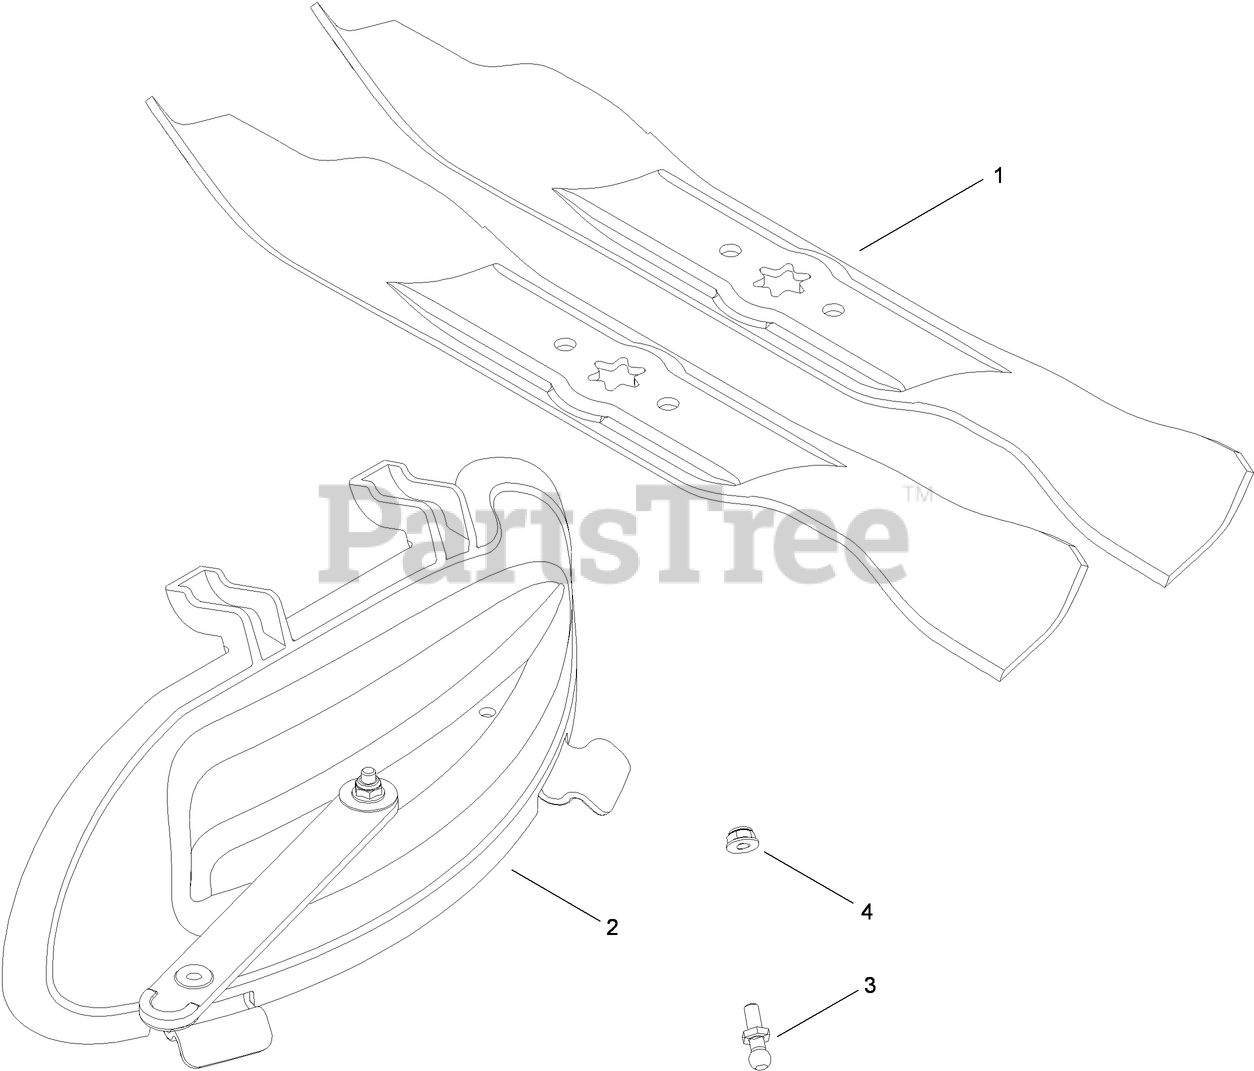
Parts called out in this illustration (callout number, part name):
2	PLUG-MULCH
3	PIN-CATCHER, GRASS
4	NUT-LOCK, FLANGE
